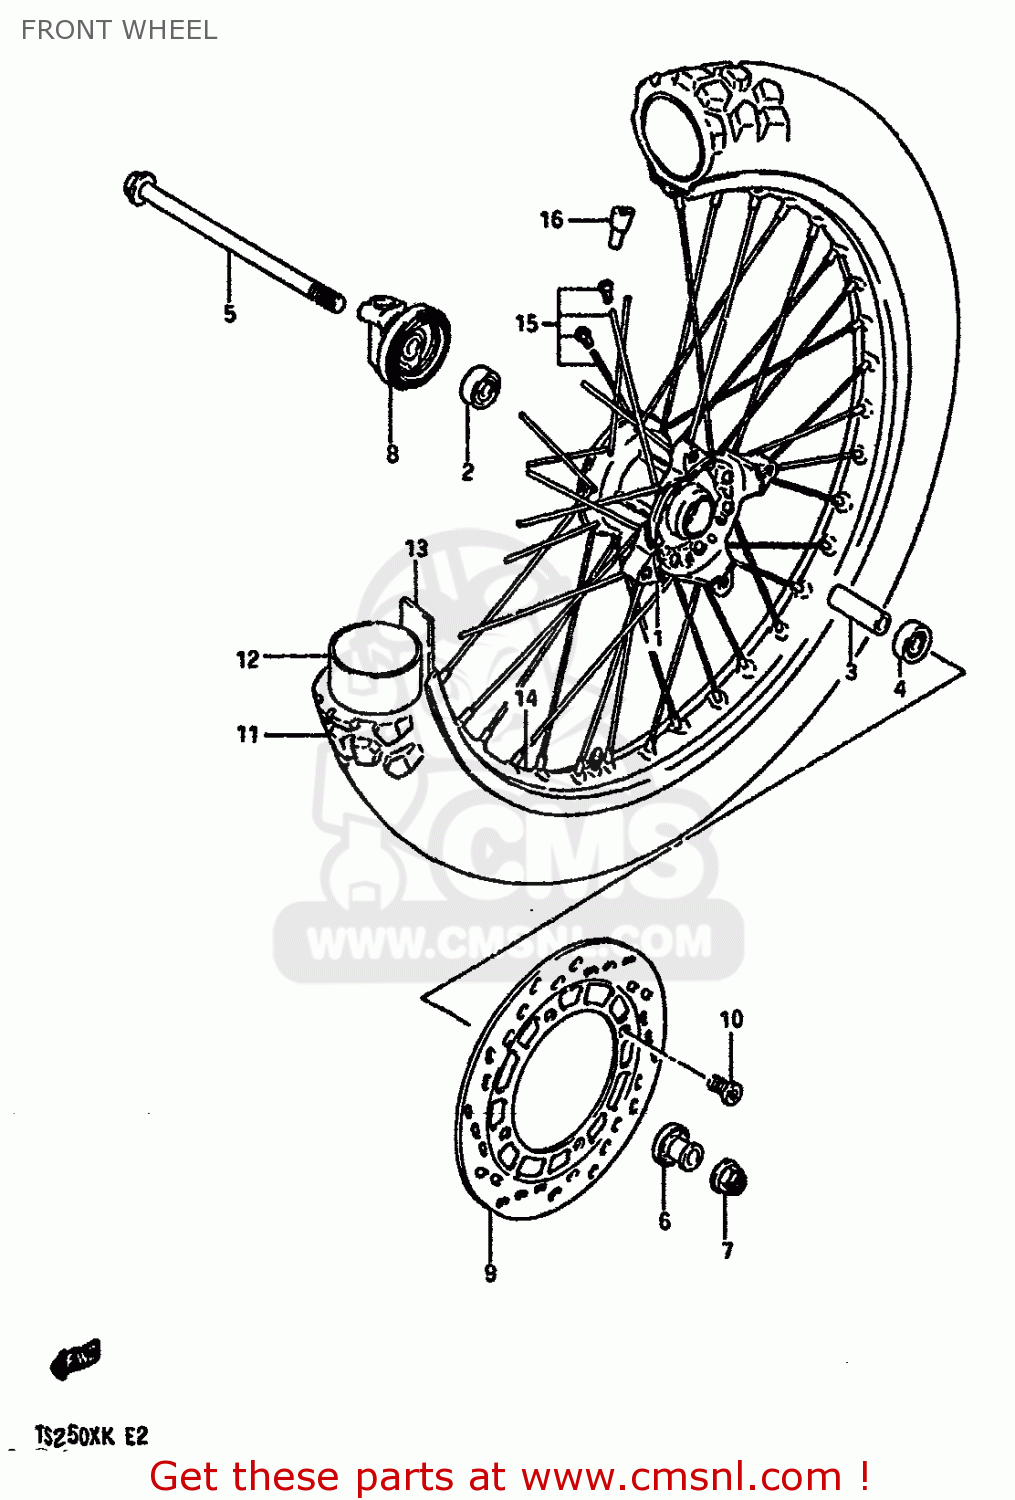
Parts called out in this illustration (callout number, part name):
1	HUB,FRONT
2	BEARING
3	SPACER (12.6X19X60.5)
4	BEARING (12X32X10)
5	AXLE,FRONT
6	SPACER,FRONT AXLE,RIGHT
7	NUT 12MM
8	BOX ASSY,SPEEDOMETER GEAR
9	DISC,FR BRAKE
10	BOLT,BRAKE DISC
11	TIRE,FRONT (3.00-21) BS
12	TUBE
13	PROTECTOR,WHEEL,INNER
14	RIM,FRONT WHEEL (1.60X21)
15	SPOKE SET,FRONT
16	BALANCER,WHEEL (50G)
